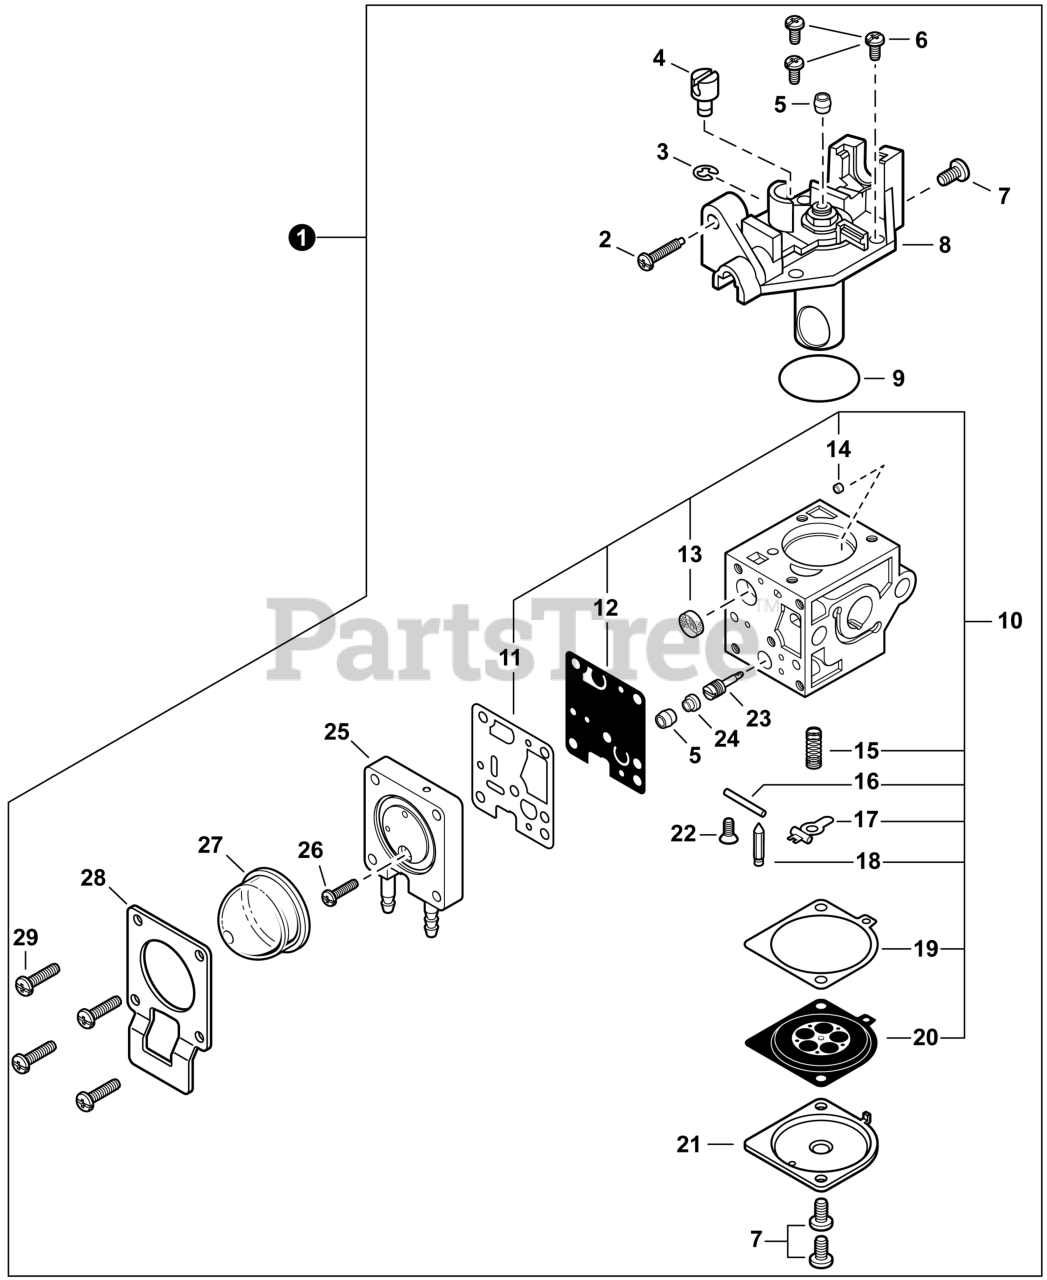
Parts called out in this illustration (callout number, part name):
1	CARBURETOR - GL-2
2	SCREW, THROTTLE ADJUST
5	CAP, LIMITER
8	COVER ASSY, ROTOR
10	REPAIR KIT
11	GASKET, PUMP
12	DIAPHRAGM, PUMP
13	SCREEN, FUEL INLET
14	GUIDE, ROLLER
15	SPRING, METERING LEVER
16	PIN, METERING LEVER
17	LEVER, METERING
18	VALVE, INLET NEEDLE
19	GASKET, METERING DIAPHRAGM
20	DIAPHRAGM, METERING
21	COVER, METERING DIAPHRAGM
23	NEEDLE, HIGH SPEED
24	CAP, LIMITER
25	BODY ASSY, PURGE
26	SCREW
27	BULB, PURGE
28	RETAINER, PURGE BULB
